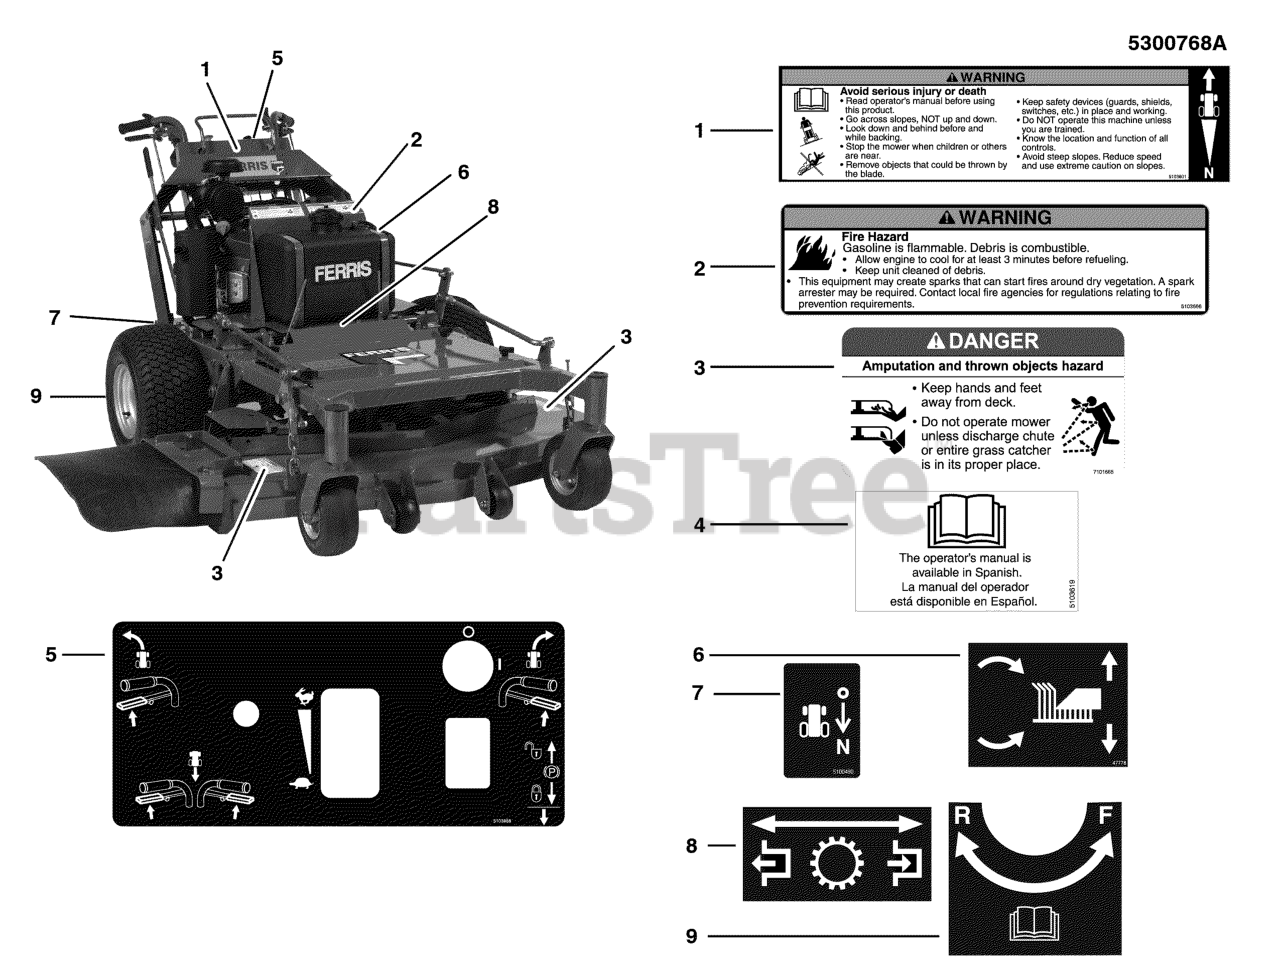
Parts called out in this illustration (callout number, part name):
1	DECAL, WARNING, WALKS
2	DECAL, FIRE HARARD, 6.75W X 1.75H
3	DECAL, DANGER DO NOT OPERATE W/O DEFLECT
4	DECAL, MANUAL AVAIL IN SPANISH
5	DECAL, CONROL PANEL, WB
6	DECAL-CUT HEIGHT ADJUST HYDRO CUT
7	DECAL, PEDAL
8	DECAL, HYDRO RELEASE
9	DECAL, FORWARD / REVERSE
